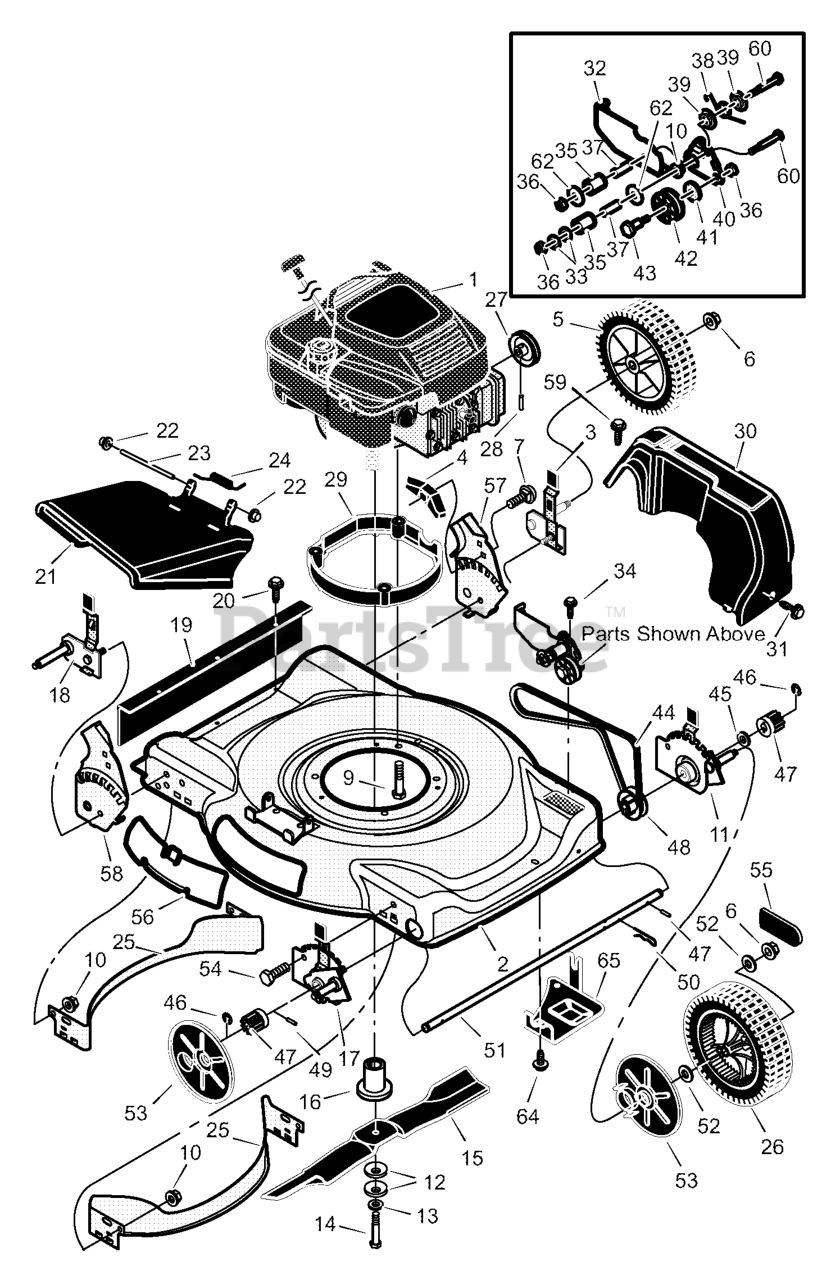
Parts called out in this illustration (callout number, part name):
1	Engine
2	Housing
3	Height Adjuster, Left Rear
5	Wheel and Tire, Rear
6	Locknut, Flange
7	Bolt, Carriage
9	Bolt, Engine
10	Nut
11	Height Adjuster, Left Front
12	Washer, Belleville
14	Bolt, Hex
15	Blade, Mulcher
16	Adapter, Blade
17	Height, Adjuster, Right Frt.
18	Height, Adjuster, Right Rr.
19	Guard, Rear
21	Deflector, Chute
22	Push-On Cap
23	Pin, Pivot
26	Wheel and Tire, Drive
28	Pin, Spring
29	Base, Engine
30	Cover, Belt (Black)
32	Bracket, Idler Support
33	Washer
35	Idler, Backside
36	Locknut
37	Bearing
40	Arm, Pivot
42	Pulley, Idler
43	Bolt, Shoulder
44	Belt, Tecumseh
46	Ring, Retainer
47	Gear, Pinion
49	Pin, Drive
50	Pin, Hair
52	Washer
53	Cover, Dust
54	Bolt
55	Hub Cap
56	Plate, Mulcher
57	Bracket, Left Handle
58	Bracket, Right Handle
65	Shield, Debris
